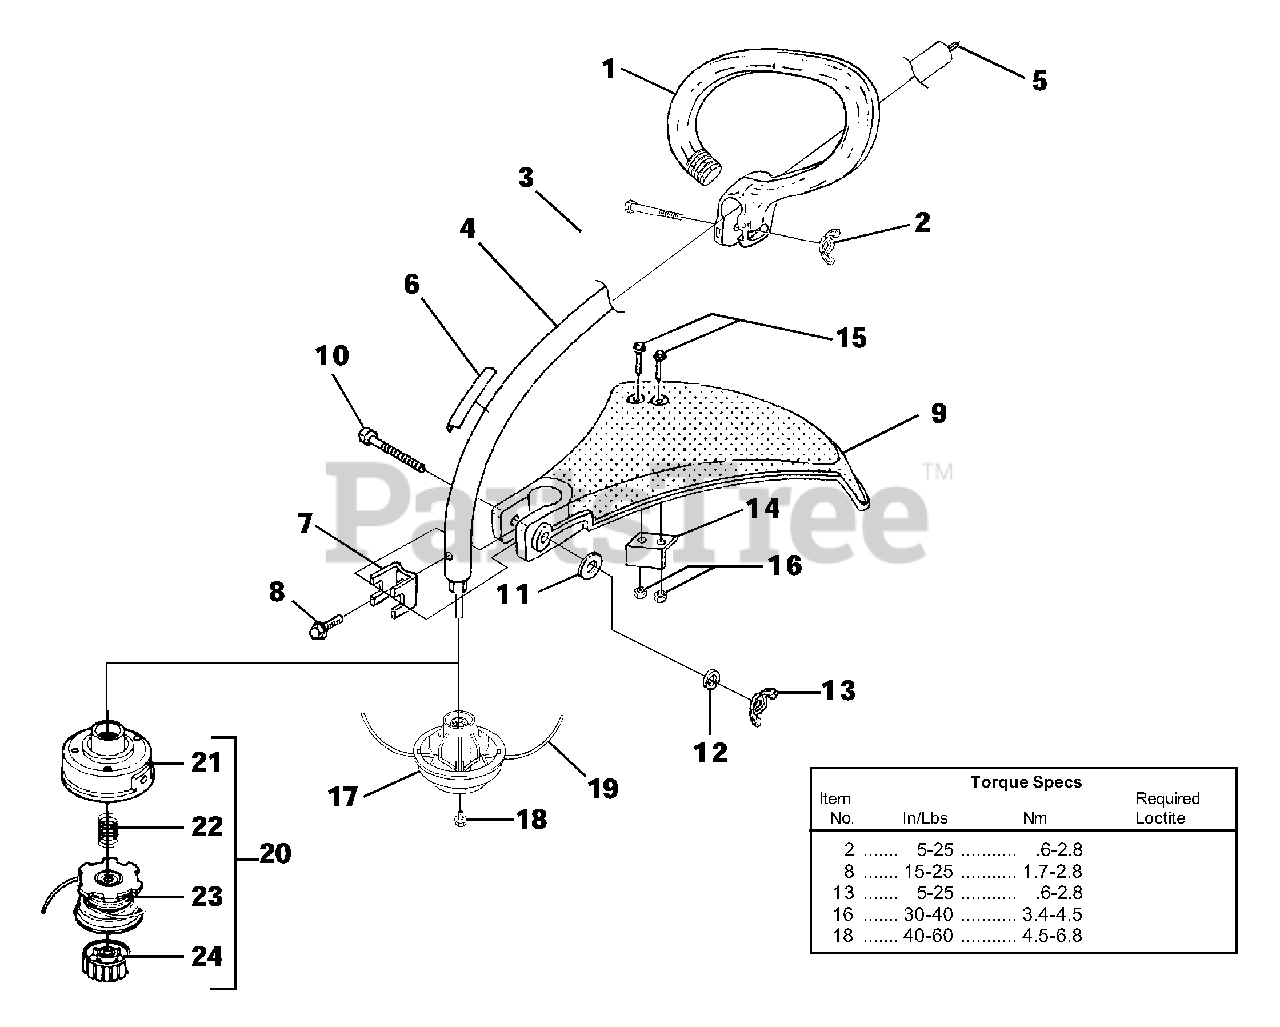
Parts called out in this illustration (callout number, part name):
1	HANDLE-Anti-Vibe
2	NUT-Wing, Washer Faced (1/4-20)
3	SCREW-Cap Hex Hd.
4	DRIVESHAFT HOUSING ASSY.
5	SHAFT-Flexible
6	DECAL-Warning
7	CLAMP
8	SCREW-Sems Hex Hd. (#10-24 X 3/8")
9	DEFLECTOR & BLADE KIT (55 Deg.)
10	SCREW-Cap Hex Hd. (10-24 X 2")
11	WASHER-Flat (1/4")
12	WASHER-Lock (1/4")
13	NUT-Wing, Washer Faced (1/4-20)
14	BLADE-Cut-Off
15	SCREW-Mech. Hex Hd. (10-24 X 7/8")
16	NUT-Hex (10-24)
17	STRINGHEAD-Pro-Cut w/line (UT20693, UT20705)
18	SCREW (5/16-18 x 5/8")
19	LINE-Replacement
20	STRINGHEAD-Complete (.080") (UT20726R, UT20823)
21	HOUSING & EYELET (Dual Line)
22	SPRING-Compression
23	SPOOL & STRING (.080")
24	RETAINER-Spool (R.H. Thread, Black)
